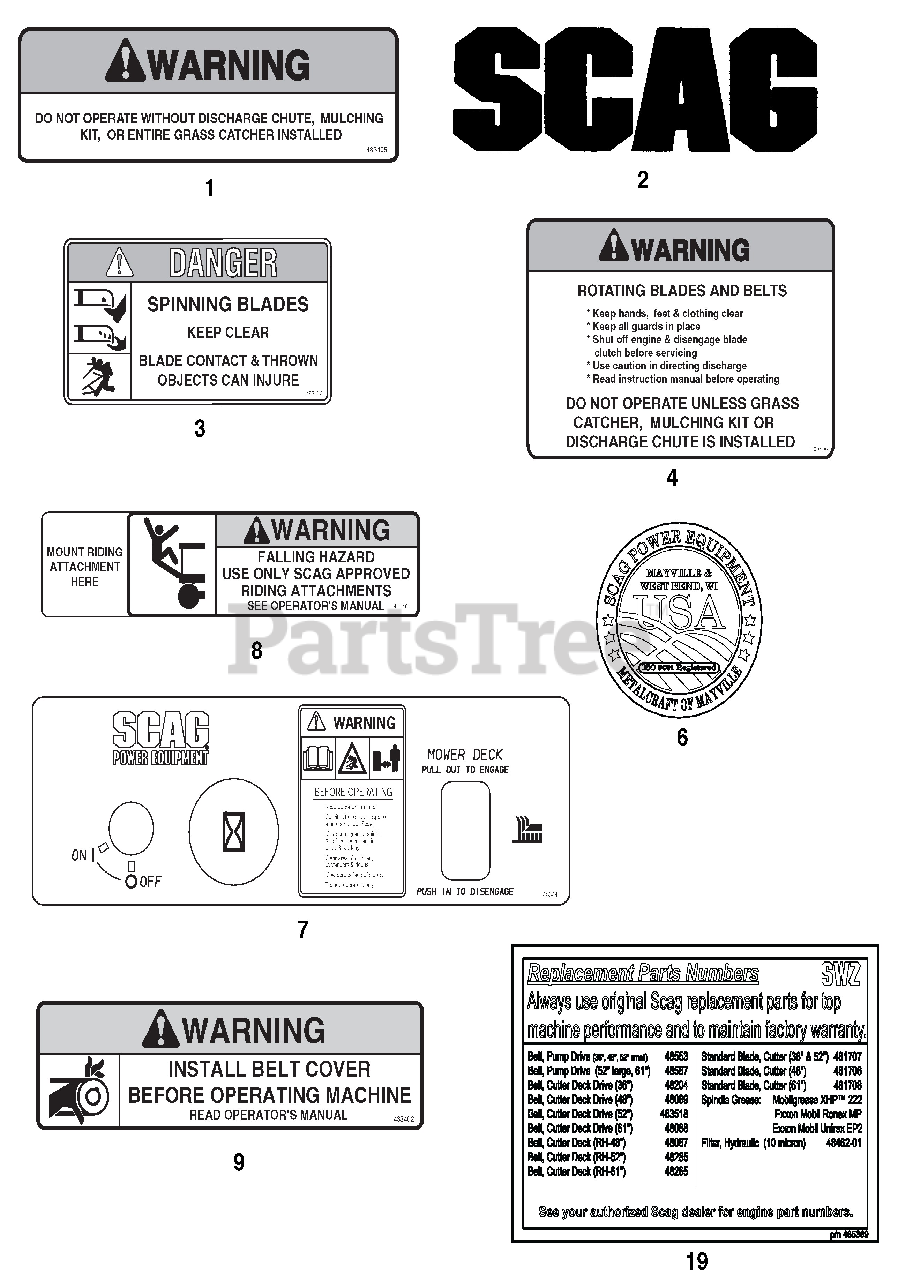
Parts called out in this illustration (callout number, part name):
1	Decal, Discharge Chute
2	Decal, Scag Logo
3	Decal, Danger-Spinning Blades
4	Decal, Warning-Rotating Blades
6	Decal, Metalcraft - USA
7	Decal, Instrument Panel - Rear
8	Decal, Sulky Attachment
9	Decal, Belt Cover
19	Decal, SWZ Replacement Parts
